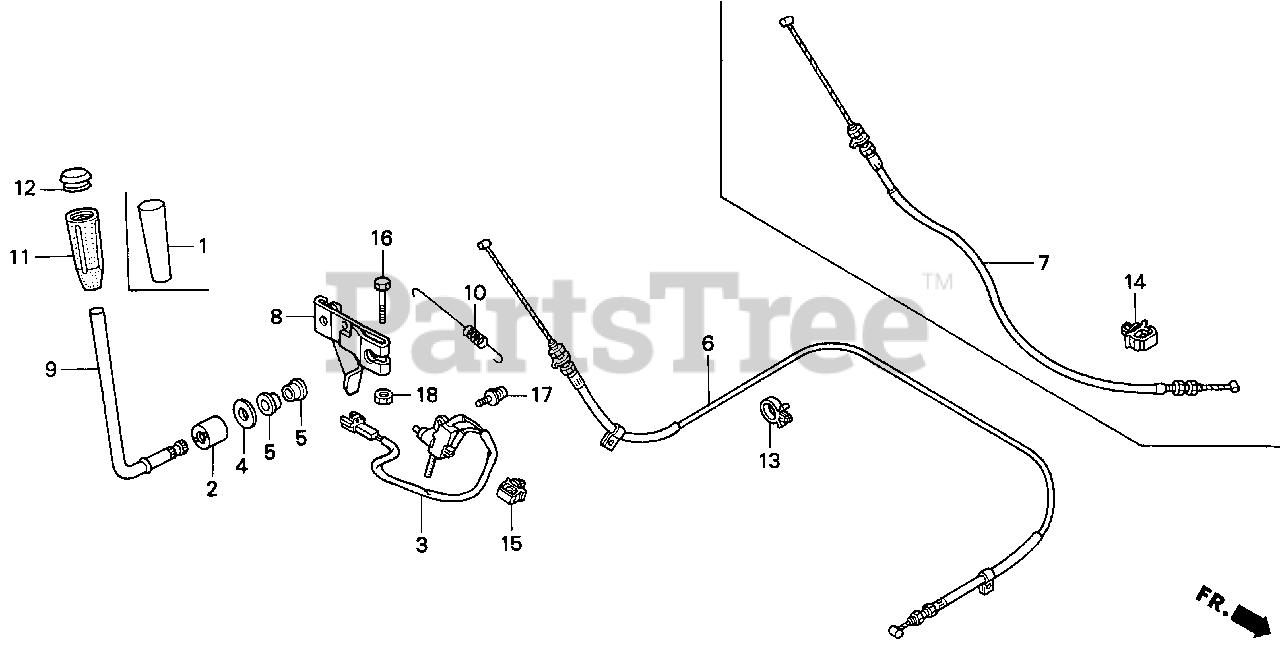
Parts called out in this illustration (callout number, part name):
1	GRIP, P.T.O. CLUTCH LEVER *Y121* (YELLOW)
2	SEAL, IGNITION TERMINAL
3	SWITCH ASSY., P.T.O. CLUTCH
4	PLATE, STOPPER
5	BUSH A, CHANGE LEVER
7	CABLE, P.T.O. CLUTCH
8	ARM, P.T.O. CLUTCH LEVER
9	LEVER, P.T.O. CLUTCH
10	SPRING, P.T.O. CLUTCH
14	CLIP, HARNESS (15MM) (BLUE)
15	CLIP, WIRE HARNESS
16	BOLT, HEX. (6X32)
17	SCREW-WASHER (4X12)
18	NUT, HEX. (6MM)
